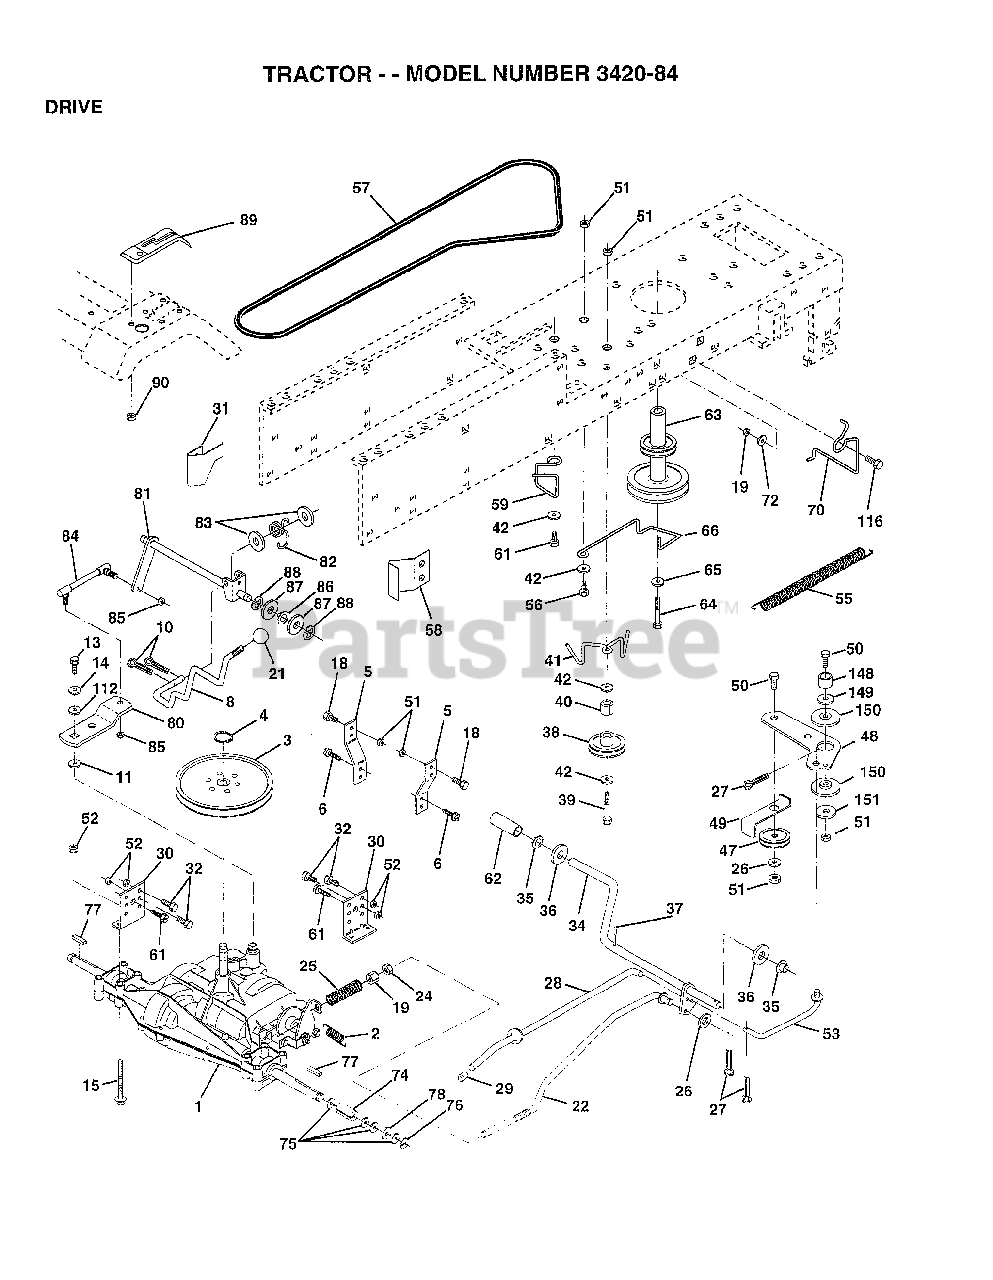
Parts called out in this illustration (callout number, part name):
2	SPRING.BRAKE.RETU
3	PULLEY TRANS
5	STRAP TORQUE
6	SCREW
8	ROD SHIFT FEND YT
10	PIN COTTER 1/8
11	WASH-SHFT PLT LT
13	BOLT.1/4-28.W/PAT
14	LOCKWASHER
15	BOLT.HX.FLG.5/16
18	BOLT
19	NUT
21	KNOB T (1/2-HOLE)
22	BRAKE ROD
24	NUT
25	SPRING ROD LT
26	WASHER
27	COTTER PIN
28	ROD.BRAKE.PARK.LT
29	PLUNGER CAP T
30	TRANSAXLE MTG BKT
31	"KEEPER,BELT LH T"
32	BOLT
34	SHAFT ASM-PEDAL F
35	NYLON BEARING
36	WASHER LT
38	PULLEY.IDLER.FLAT
39	BOLT
40	SPACER T
42	WASHER
48	BELLCRANK.CLUTCH
49	RETAIN BELT
53	"LINK, CLUTCH T"
55	"SPRING, RETURN LT"
57	"V-BELT,95.3"
58	"KEEPER,BELT RH T"
59	KEEPER BELT CNTSP
61	SCREW
62	PEDAL COVER T
63	PULLEY.ENGINE
64	BOLT
65	LOCKWASHER
66	KEEPER-BELT
70	KEEPER BELT ENG
72	WASHER
74	SPACER LT
75	WASHER
76	E-RING LT
77	SQUARE KEY
78	WASHER
80	ARM.SHIFT.TRANS.
81	SHAFT ASSY CROSS
82	"SPRING,TORSION"
83	WASHER
84	"ROD.TIE.20""P930LT"
85	NUT.CNT.LOCK.1/4
86	BUSHING
87	WASHER D
88	KLIP RING
89	CONSOLE SHIFT
90	NUT
112	WASHER LT
113	"STRAP,TORQUE"
116	BOLT RDHD 3/8-16
118	SPACER-BELLCRANK
121	NYLINER-CLUTCHING
149	SPACER RETAINER
150	BUSHING.NYLON
151	WASHER
